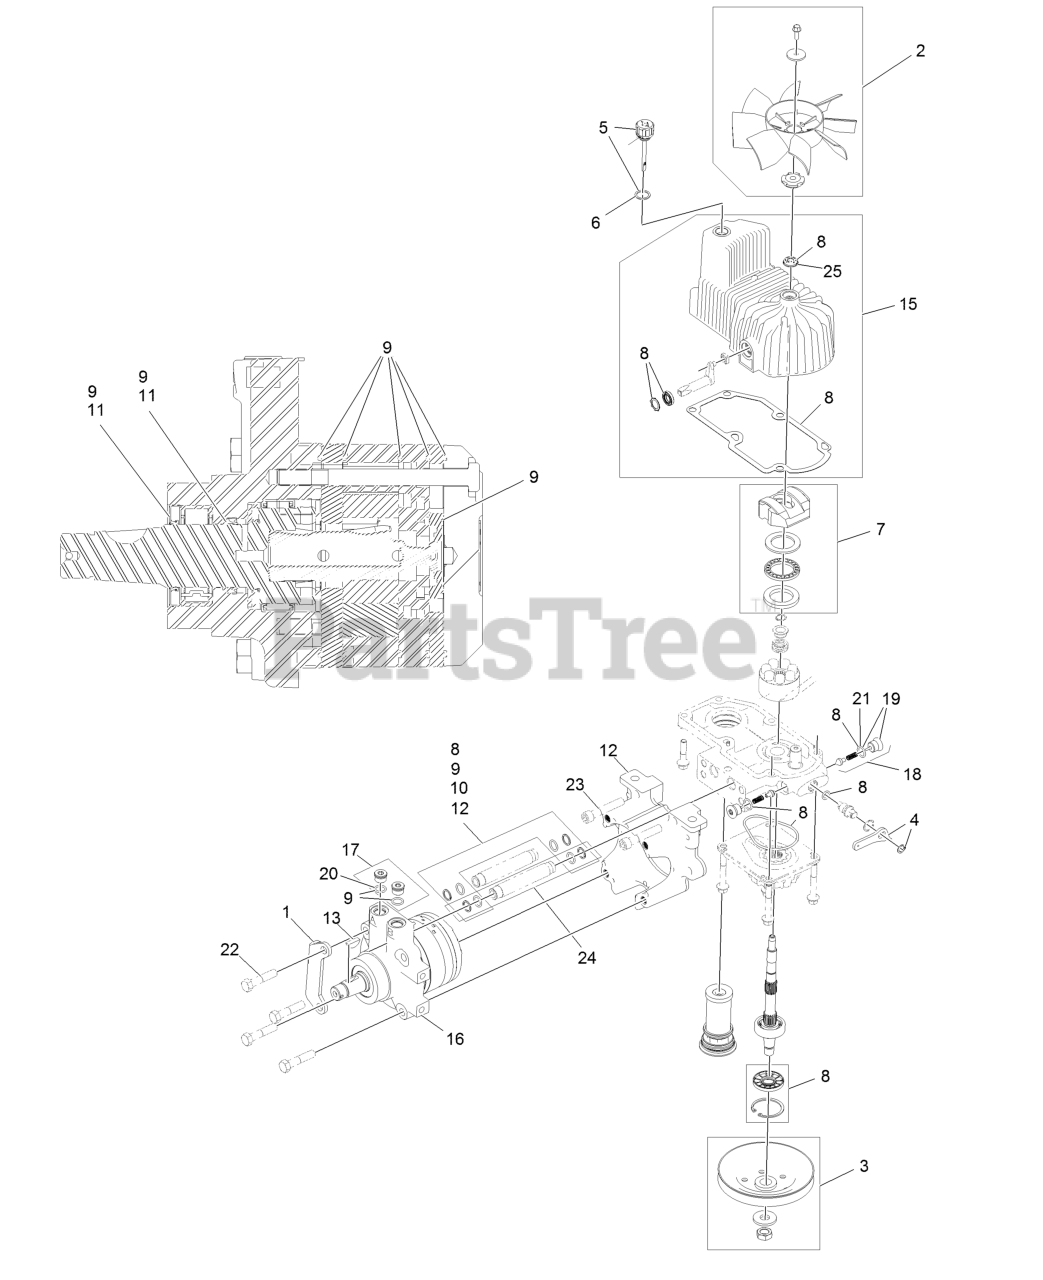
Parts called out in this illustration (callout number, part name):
1	MOUNT-SHOE, HORSE
2	FAN KIT
3	PULLEY KIT
4	HANDLE-BYPASS VALVE, HYDRO
5	DIPSTICK-HYDRO W/GASKET
6	GASKET-DIPSTICK, HYDRO
7	SWASH BLOCK KIT
8	PUMP SEAL KIT
9	MOTOR SEAL KIT
10	TUBE SEAL KIT
11	OUTPUT SHAFT SEAL KIT
12	NOSE CUP-UHT
13	KEY-WOODRUFF
15	HOUSING-HYDRO, RH
16	MOTOR-HYDRAULIC RH 240CC
17	MAGNETIC PLUGS SERVICE KIT
18	CHECK VALVE ASM
19	PLUG-CHECK (W/O-RING)
21	O-RING-CHECK VALVE
22	SCREW HH
23	SCREW-HSH
24	HYDRAULIC TUBE KIT
25	SEAL-FAN DRIVE
